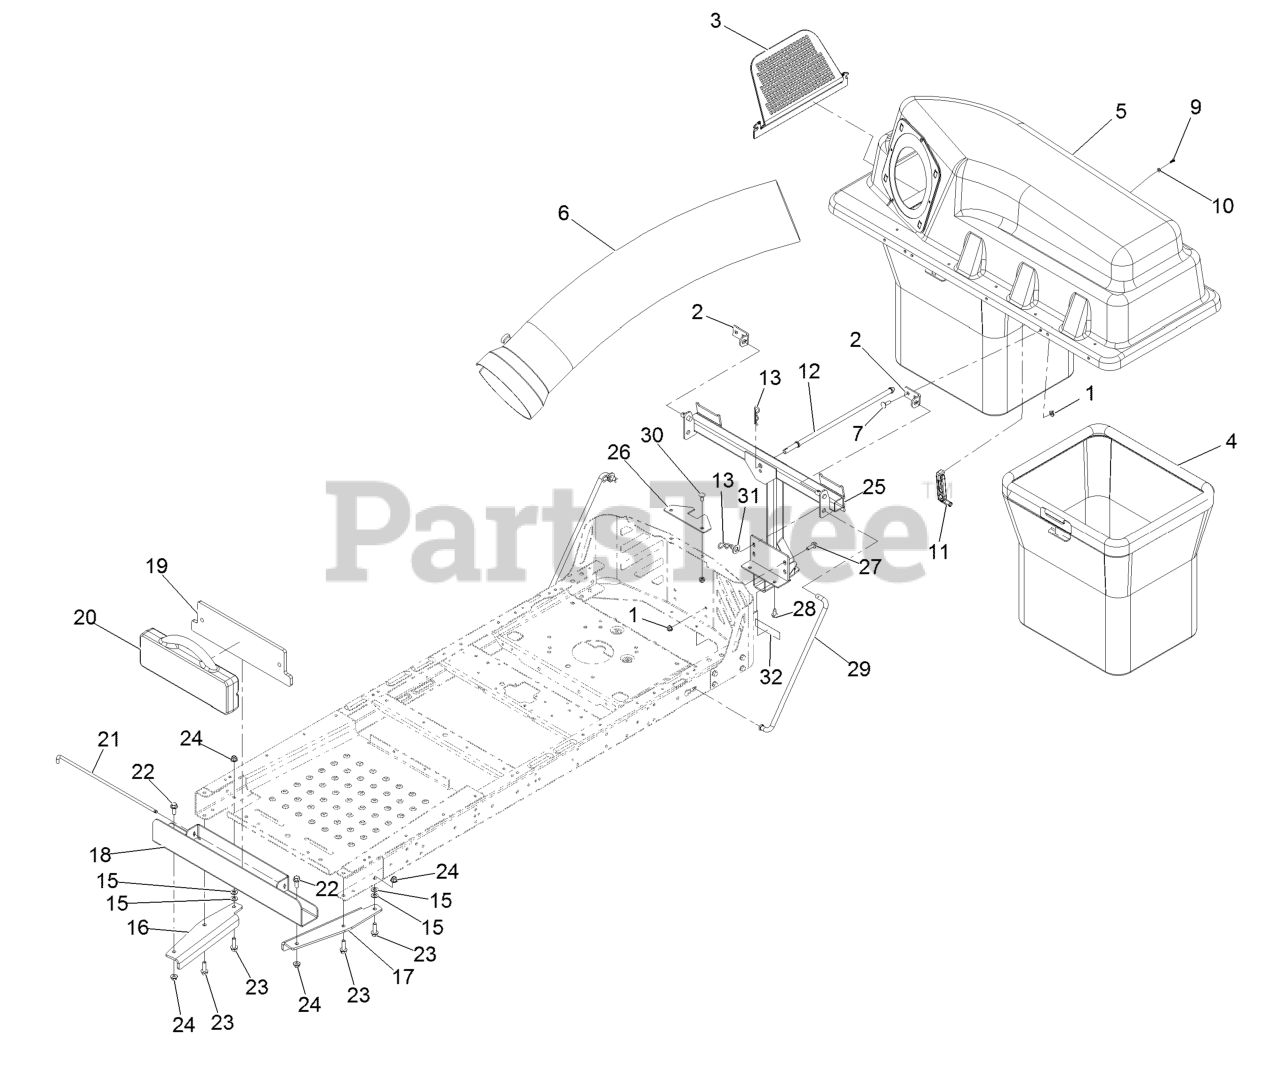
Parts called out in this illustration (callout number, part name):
1	Nut-HF, NI
2	Bracket-Pivot, Hopper
3	Screen-Bagger
4	Bag ASM
5	Bagger Top ASM
6	Tube-Bagger
7	Bolt-CARR
9	Screw-Plastite
10	Washer-Flat
11	Latch-Rubber
12	Rod-Hood, Down (Hold)
13	Pin-Hair
15	Washer-Flat
16	Bracket-Bagger Weight, RH
17	Bracket-Bagger Weight, LH
18	Channel-Weight, Bagger
20	Weight-35 Pound
21	Pin-Weight
22	Screw-HHF
23	Screw-HHF
24	Nut-HF, NI
25	Pivot Frame ASM
26	Bracket-Stabilizer
27	Screw-HHF
28	Screw-HWHTF
29	Rod-Support
30	Bolt-CARR
31	Washer-Flat
